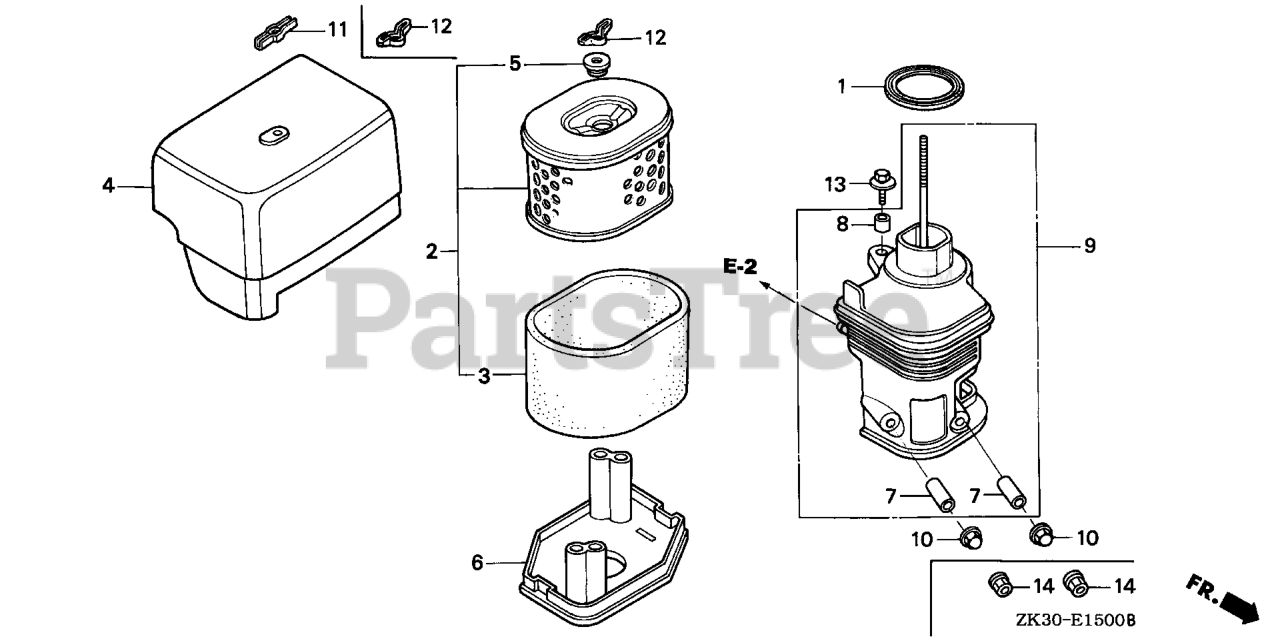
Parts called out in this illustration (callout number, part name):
1	GASKET, ELBOW
2	ELEMENT, AIR CLEANER
3	FILTER (OUTER)
4	COVER, AIR CLEANER
5	GROMMET, AIR CLEANER
6	NOSE, MUFFLER
7	COLLAR, AIR CLEANER
8	COLLAR B, AIR CLEANER
9	ELBOW, AIR CLEANER
11	WINGNUT (6MM)
12	WINGNUT, TOOL BOX SETTING
13	BOLT-WASHER (6X20)
14	NUT, FLANGE (6MM)
